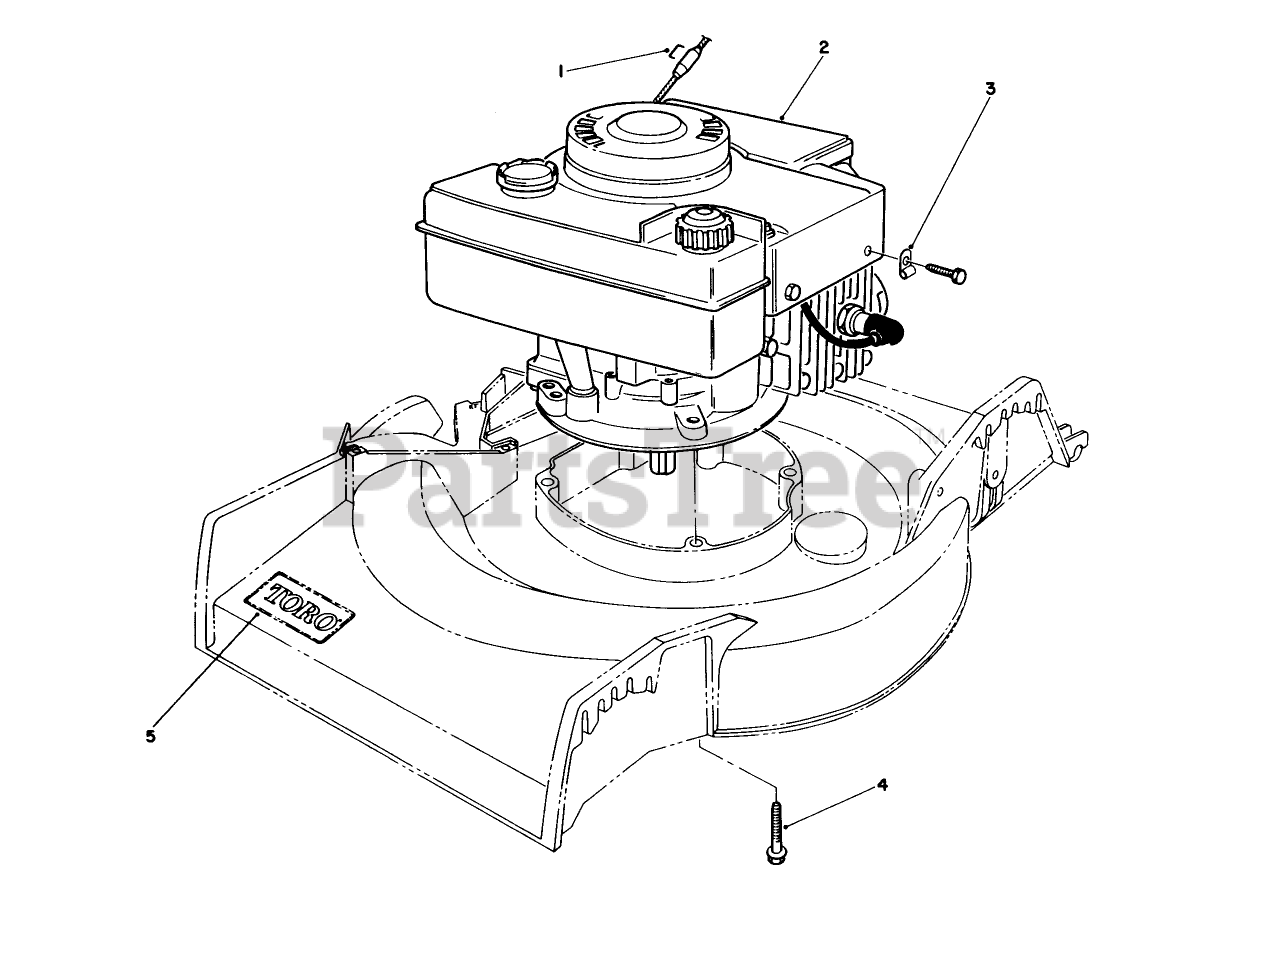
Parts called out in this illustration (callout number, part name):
1	Staple
2	Engine
4	3/8-16 X 2-3/4 CAPSCR
5	DECAL
